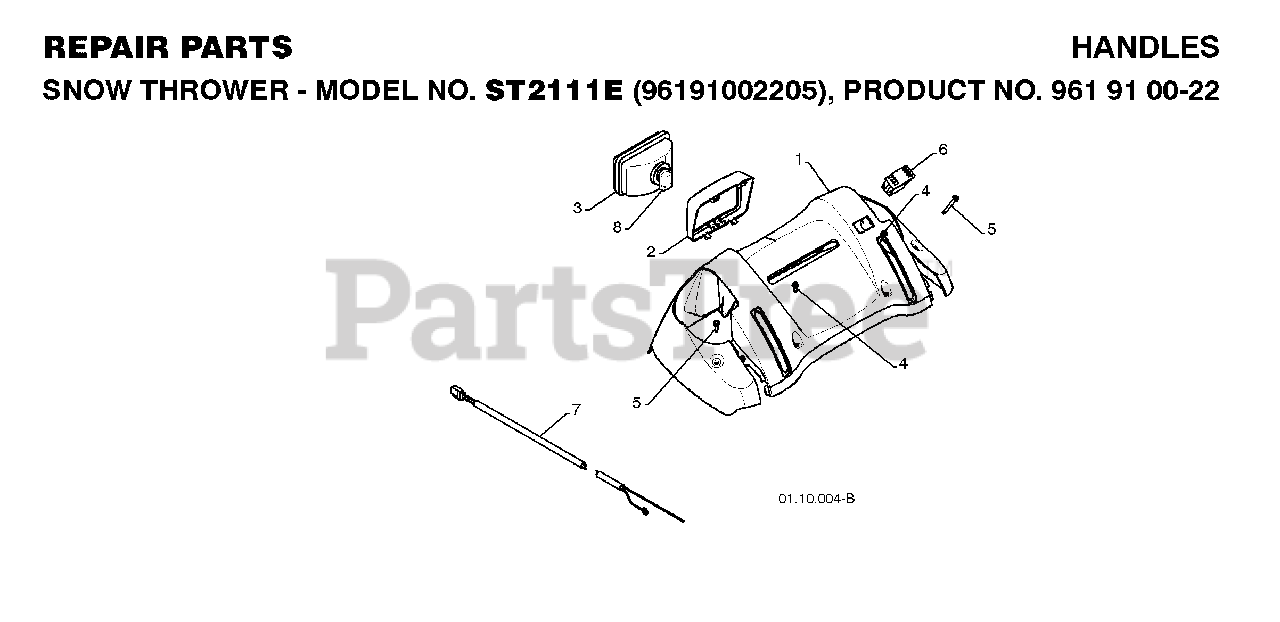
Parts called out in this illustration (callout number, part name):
2	BEZEL.HEADLIGHT.BLACK
3	HEADLIGHT, HALOGEN
4	SCREW, HEX HEAD, TAPPING
5	SCREW, HEX HD TAPPING #10-24 1
6	SWITCH.HEATED.GRIP
7	HARNESS.WIRE.LIGHT/GRIP.SNOW
8	BULB.HEADLIGHT.HALOGEN.
